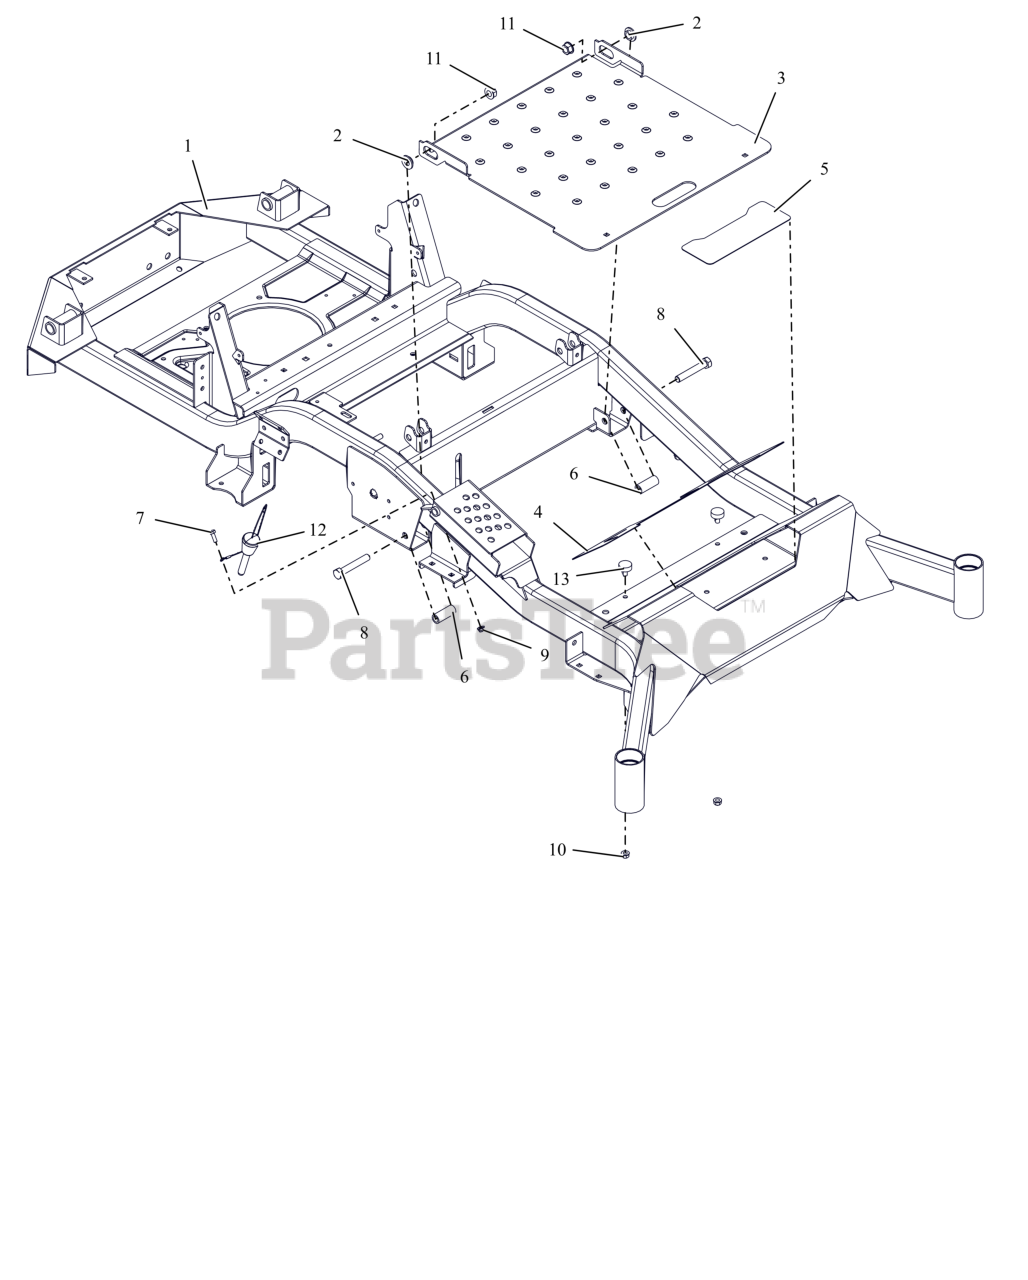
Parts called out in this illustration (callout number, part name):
1	APEX 60"FRAME W/SAFTETY DECALS
2	BSHG-FLG .515X.750X.395X1.120
3	PANEL, ACCESS
4	GRIP, FRONT
5	GRIP, STEP
6	SPACER, .515X.75X1.83
7	BLT, HEX .25-20X.75 G5 ZCC
8	BLT, HEX .50-13X3.00 G5 ZCC
9	NUT,NYL-FLG .25-20 GF ZCC
10	NUT,SPNLK-FLG .31-18 G5 ZCC
11	NUT-LK-TOP-FLG .500-13 GF ZCC
12	PIN, MAGNETIC .50X2.50
13	BUMPER, RUBBER
